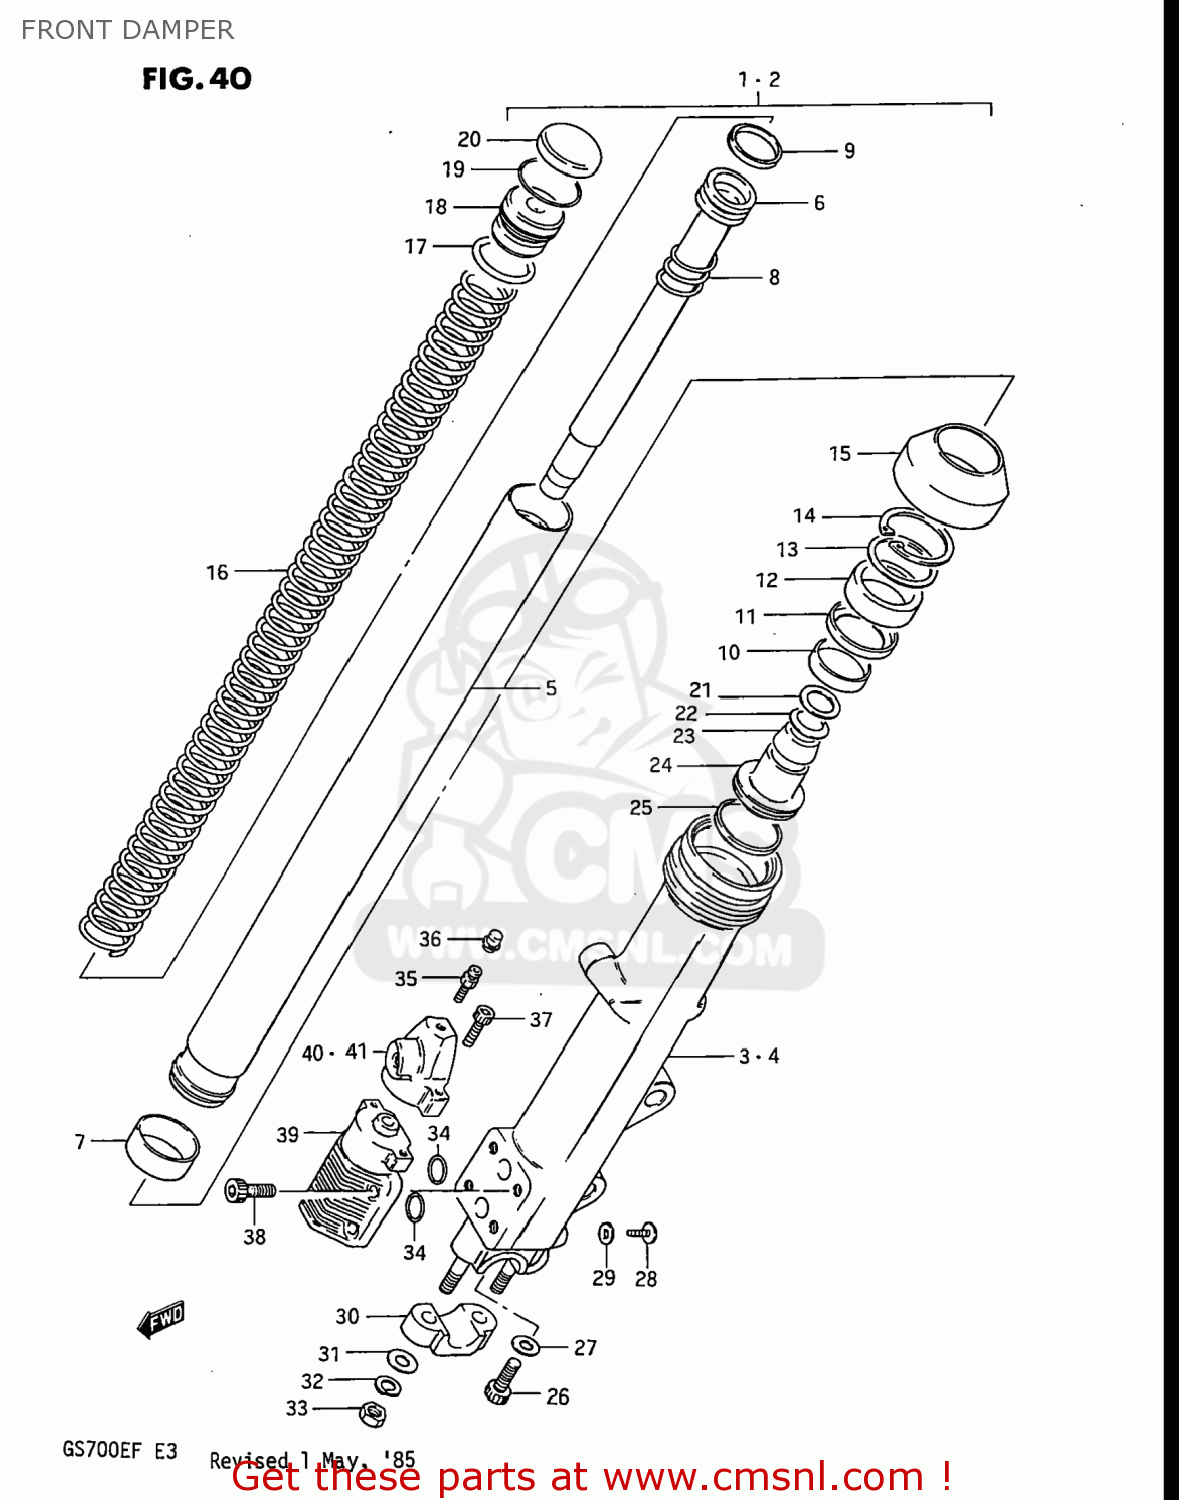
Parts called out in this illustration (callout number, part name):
1	DAMPER ASSEMBLY,RIGHT
2	DAMPER ASSEMBLY,LEFT
3	TUBE,OUTER,RIGHT
4	TUBE,OUTER,LEFT
5	TUBE,FORK,INNER
6	CYLINDER,FRONT FORK
7	PISTON
8	SPRING,FORK REBOUND
9	RING,PISTON
10	BUSHING,GUIDE
11	SPACER,SEAL
12	OIL SEAL,FRONT FORK
13	RING,BACKUP
14	CIRCLIP,INNTERNAL
15	BOOT
16	SPRING
17	O RING
18	SEAT,FRONT FORK SPRING
19	STOPPER RING,FORK SPRING
20	CAP,FRONT FORK
21	VALVE
22	SPRING,VALVE
23	VALVE,OIL LOCK PIEACE
24	PIECE,OIL LOCK
25	RING,PISTON
26	BOLT(8X27)
27	GASKET (NAS)
28	SCREW 4X6
29	GASKET (NAS)
30	HOLDER,AXLE
31	WASHER
32	WASHER,LOCK,8.
33	NUT
34	O RING,FR FORK
35	BREATHER
36	CAP
37	BOLT
38	BOLT
39	VALVE SET,MODULATOR
40	PLUNGER SET,MODULATOR,RIGHT
41	PLUNGER SET,MODULATOR,LEFT
